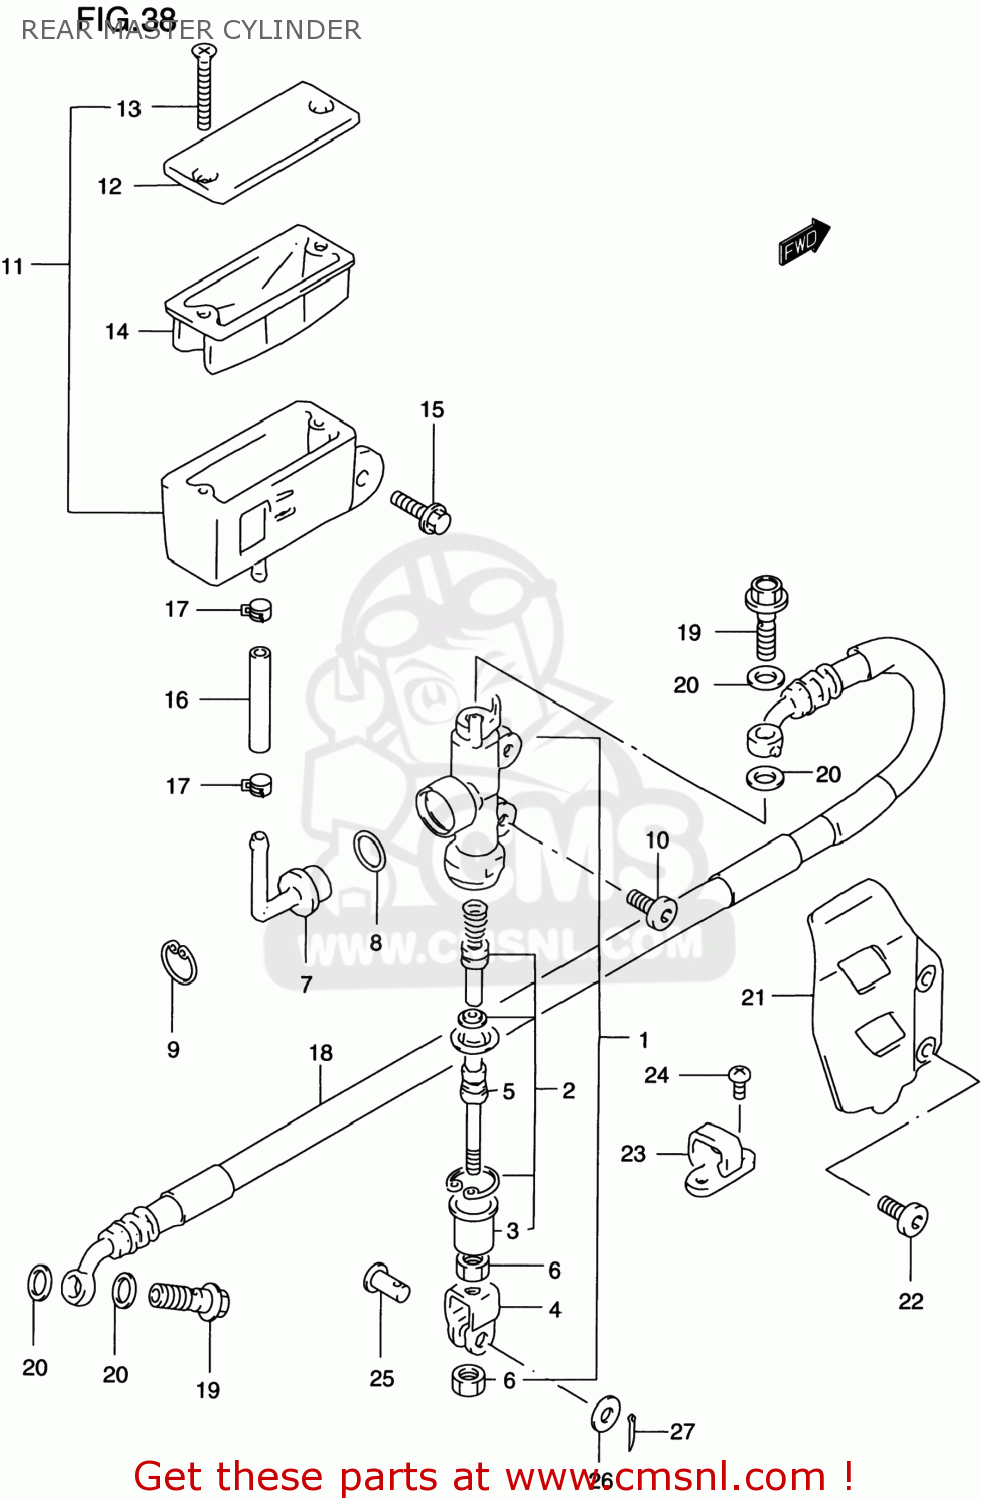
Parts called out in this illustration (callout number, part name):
1	CYLINDER ASSY,RR MASTER
2	PISTON/CUP SET
3	BOOT
4	YOKE
5	ROD,PUSH
6	NUT
7	CONNECTOR
8	O RING
9	CIRCLIP
10	SCREW(6X16)
11	TANK ASSY,RESERVOIR
12	CAP
13	SCREW
14	DIAPHRAGM
15	BOLT
16	HOSE,FR RESERVOIR TANK
17	CLAMP,RESERVOIR HOSE
18	HOSE COMP,REAR BRAKE
19	BOLT UNION
20	WASHER(10X15X1.5)
21	GUARD,RR MASTER CYLINDER
22	SCREW(6X16)
23	GUIDE,RR BRAKE
24	SCREW
25	PIN(8X20)
26	WASHER(8.5X13X1.6)
27	PIN
